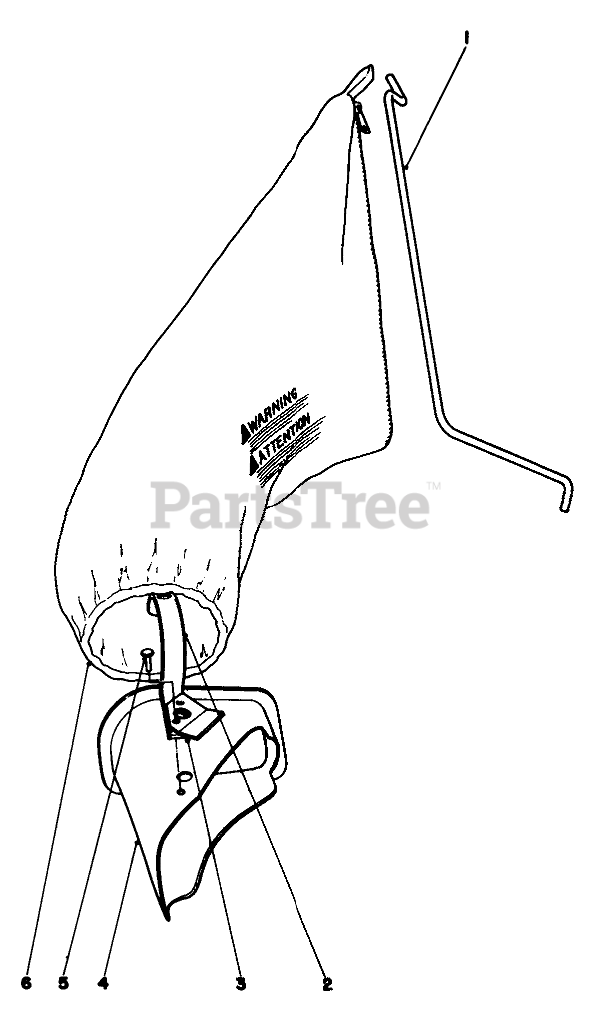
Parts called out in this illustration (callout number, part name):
1	BAG HANGER ROD
2	BAG CHUTE HANDLE
3	Stop Deflector
4	Grass Chute (Incl. Ref. #2&4-5)
5	Rivet Semi Tubular
6	BAG REPLACMNT44-0540
